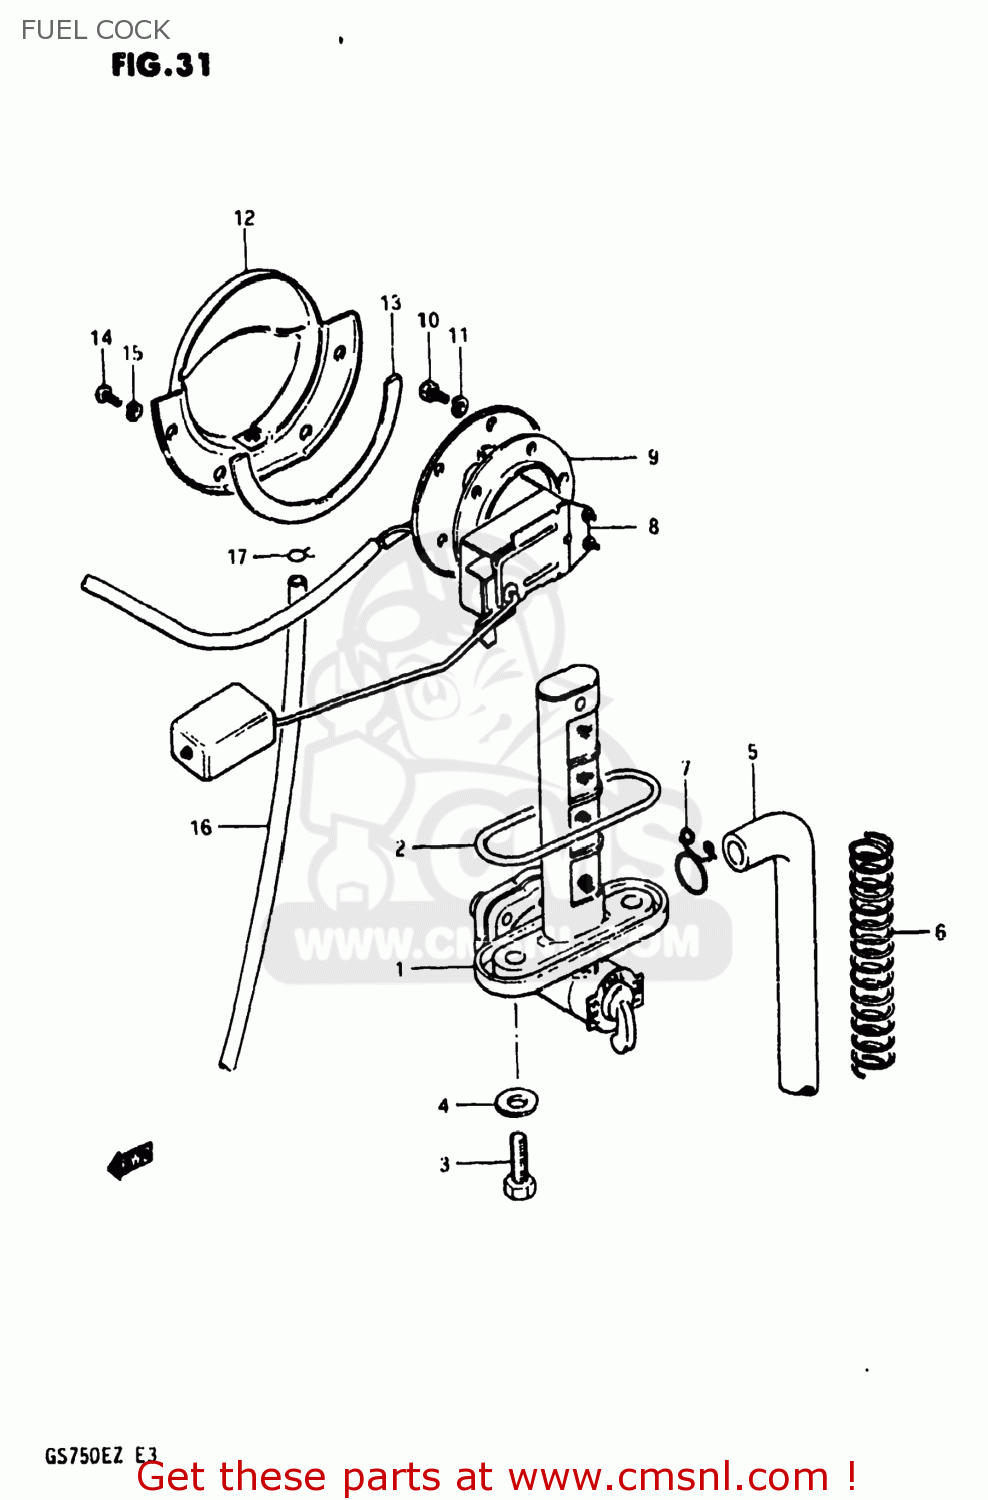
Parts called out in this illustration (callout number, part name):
1	COCK ASSEMBLY,FUEL
2	O RING
3	SCREW (6X25)
4	GASKET
5	HOSE
6	SPRING
7	CLIP
8	GAUGE ASSEMBLY,FUEL LEVEL
9	GASKET,FUEL LEVEL GAUGE (NAS)
10	BOLT
11	LOCK WASHER
12	PLATE,FUEL DRAIN
13	GASKET (NAS)
14	SCREW
15	LOCK WASHER
16	HOSE,FUEL
17	CLIP
